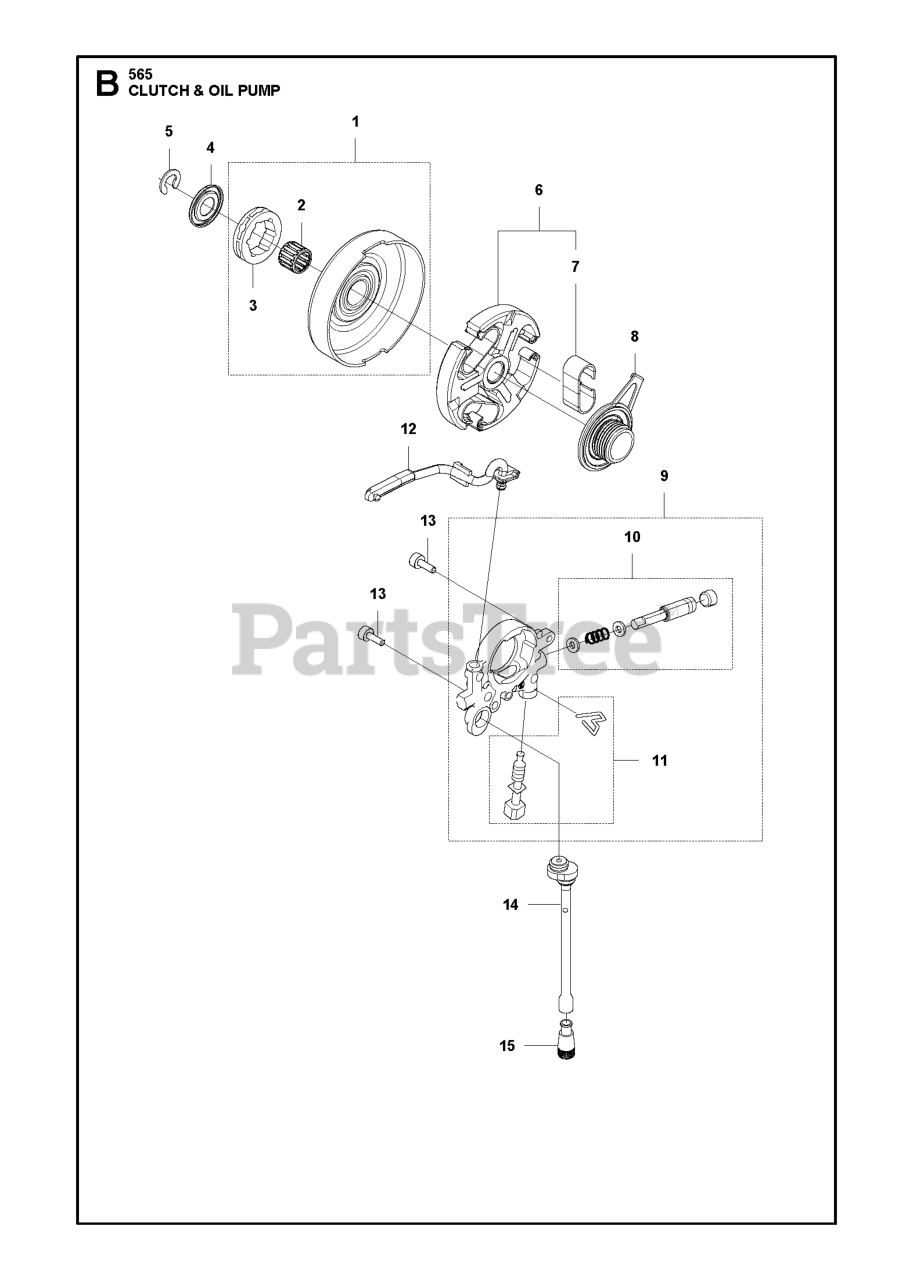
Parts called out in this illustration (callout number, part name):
1	CLUTCH DRUM ASSY
2	CLUTCH DRUM BEARING
3	68210 RIMSPROCKET
5	RETAINING RING
6	CLUTCH ASSY MJ14X1.25-6H, NEW
8	PUMP PINION ASSY
9	OIL PUMP ASSY
10	PUMP PISTON KIT H565/H572
11	OIL PUMP PIN SCREW KIT H565/H5
12	OIL PRESSURE HOSE
13	SCREW ITXSCM M4X15 T27 12.9 T
14	OIL HOSE ASSY 565/572
15	OIL SCREEN
